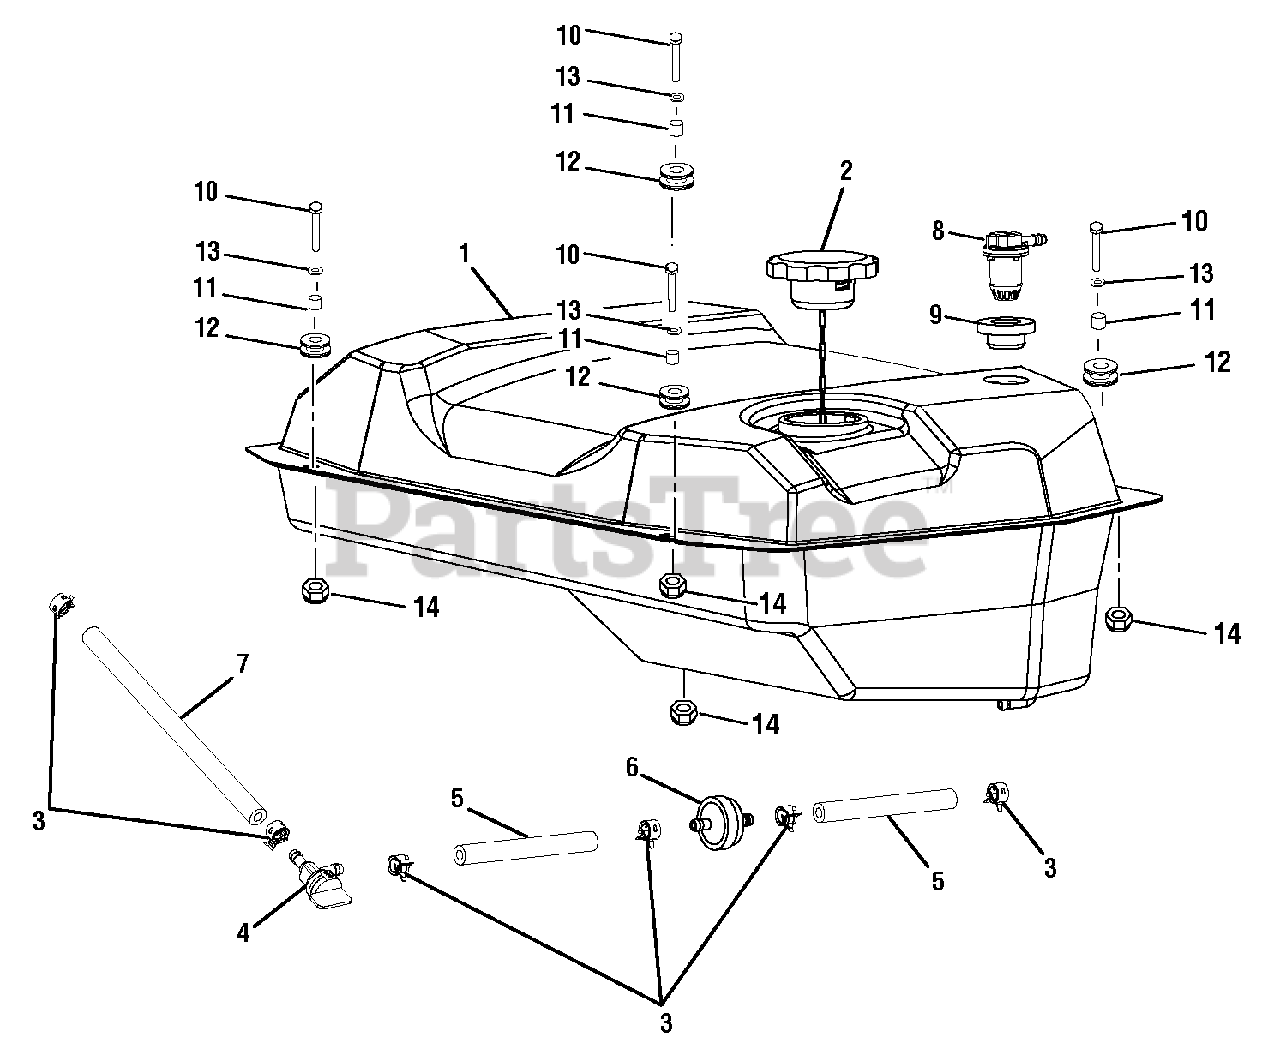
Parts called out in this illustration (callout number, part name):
1	Fuel Tank (PS905055S)
1	Fuel Tank (PS905055SA)
2	Fuel Tank Cap
3	Fuel Line Clamp (1/2 in.)
4	Fuel Shut Off Valve
5	Fuel Line (6.4 mm x 105 mm)
6	Fuel Filter
7	Fuel Line (6.4 mm x 208 mm)
8	Fuel Tank Vent Valve (PS905055S)
8	Fuel Tank Vent Valve (PS905055SA)
9	Bushing (PS905055S)
10	Bolt (1/4-20 x 1 in.)
11	Washer (1/4 in.)
12	Isolator (Fuel Tank)
13	Spacer (Fuel Tank Isolator)
14	Lock Nut (1/4-20)
